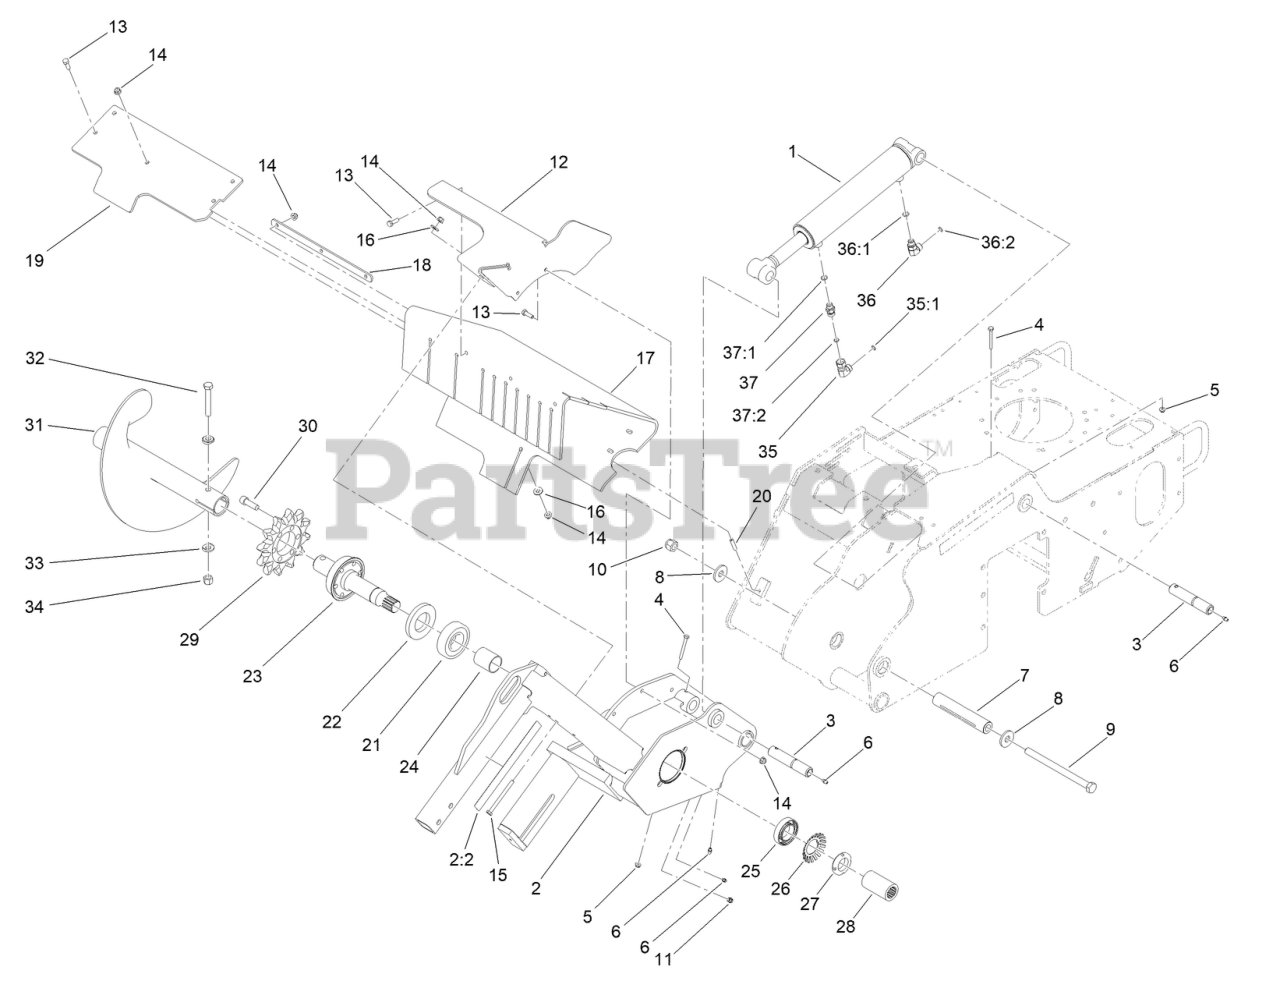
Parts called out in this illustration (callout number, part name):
1	HYDRAULIC CYLINDER ASM
2	TRENCHER HEAD ASM
2:2	DECAL-DANGER
3	PIN-PIVOT
4	SCREW-HH
5	NUT-HF
6	FITTING-GREASE
7	SPACER-PIVOT
8	WASHER-HARDENED
9	BOLT-HH
10	NUT-LOCK, NI
11	FITTING-LUBE
12	BRACKET-SHIELD
13	SCREW-HH
14	NUT-HF, NI
15	SCREW-HH
16	WASHER-FLAT
17	SHIELD-DIRT
18	PLATE-STRAP, SHIELD
19	BAR-CLAMP
20	SCREW-HSH
21	BEARING-BALL
22	SEAL-GREASE
23	SHAFT-TRENCHER
24	SPACER
25	BEARING-BALL
26	LOCKWASHER-BEARING
27	LOCKNUT-BEARING
28	COLLAR-SPLINED
29	SPROCKET-TRENCHER
30	SCREW-HSH
31	AUGER-TRENCHER
32	SCREW-HH
33	WASHER-SADDLE
34	NUT-LOCK, NI
35	FITTING-HYD, 90 DEG
35:1	O-RING
36	FITTING-ELBOW, 90 DEG
36:1	O-RING
36:2	O-RING
37	VALVE-CHECK
37:1	O-RING
37:2	O-RING
